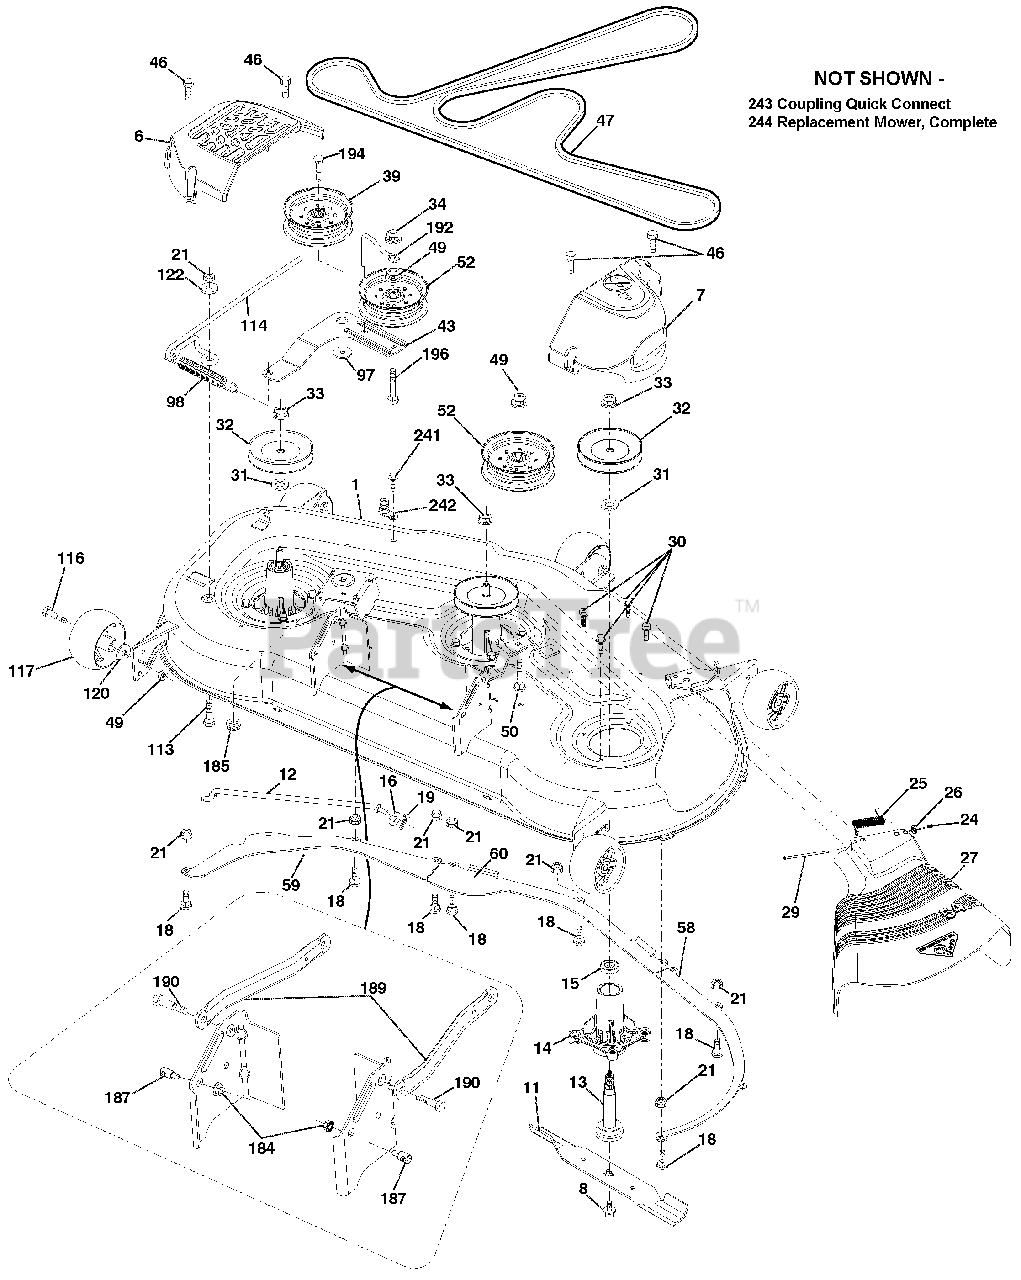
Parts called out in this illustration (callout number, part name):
1	DECK WELDMENT MOWER
6	COVER.MANDREL.LH.54"2006
7	COVER.MANDREL.RH.54"2006
8	BOLT/WASHER ASM.7/16-20.UNF
11	BLADE.BAGGING.54"
11	BLADE MULCHING
12	ROD ANTI-SWAY
13	SHAFT ASM.MANDREL.48/54"SVC
14	HOUSING.MANDREL.4PT.SERVICE
15	BEARING.BALL.MANDREL
16	Washer 13/32 x 13/16 x 12 Ga.
18	BOLT.RDHD.SQNK.5/16-18 X 5/8
19	PIN.COTTER.5/16.BOW TIE LOCK
21	Nut, Hex, Crownlock 5/16-18
24	CAP.SLEEVE..80X.112.BLK.MOWER
25	SPRING.TORSION.48"
26	NUT.PUSH.PHOS.& OIL
27	DEFLECTOR SHIELD
29	ROD.HINGE.42/46"
30	SCREW.THD ROLL.DOD PT.HEX
31	WASHER.SPACER.MANDREL
32	MANDREL.PULLEYS.42,44,50
32	MANDREL ASM.48/54"
32	ONLY (KEY #15)-PULLEY/NUT/WASHER AND BLADE BOLT/WASHERS NOT INCLUDED)
33	NUT.FLANGE.LOCK.TOP
34	Nut, Hex, Crownlock 3/8-16
39	PULLEY.IDLER.4.50.HUB.SPECIAL
43	ARM.ILDER
46	SCREW.THD.ROLL.1/4-20 X 5/8
47	BELT.DRIVE.54"2006
49	Nut, Hex, Flangelock 3/8-16
50	BOLT.RD.HD.SQ.NK.3/8-16UNC X 2
52	PULLEY.IDLER.4.50.RAW
58	BAFFLE.RIGHT.54"
59	BAFFLE.LEFT.54"
60	BAFFLE.CENTER.54"MOWER
97	WASHER.FLAT.HARDENED
98	SPRING.DRIVE.DECK.2006
113	BOLT.CARR.5/16-18UNC X 1
114	ROD.TENSION.RELIEF
116	BOLT.SHOULDER.3/8-16X3-5/8.GR5
117	WHEEL.GAUGE.RALLY.
120	WASHER.13/32 X 1-1/4 X 12 GA.
122	BUSHING.RELIEF.TENSION
184	Nut, Lock Hex Flange 5/16-18 u
185	NUT.LOCK.FLANGE.7/16-14.GR5
187	STUD.FASTNER.W/'D'ANTI-ROTATIO
189	ARM.SUSPENSION.MOWER.REAR
190	BOLT.SHOULDER
192	KEEPER.BELT.IDLER.54"TL
194	BOLT CARR SQNK 3/8-16 X 2-1/4
196	BOLT.RDHD.SQNK.3/8-16X2-1/2.G5
242	PORT WASHOUT
243	COUPLING QUICK CONNECT
244	54" REPLACEMENT MOWER COMPLETE
